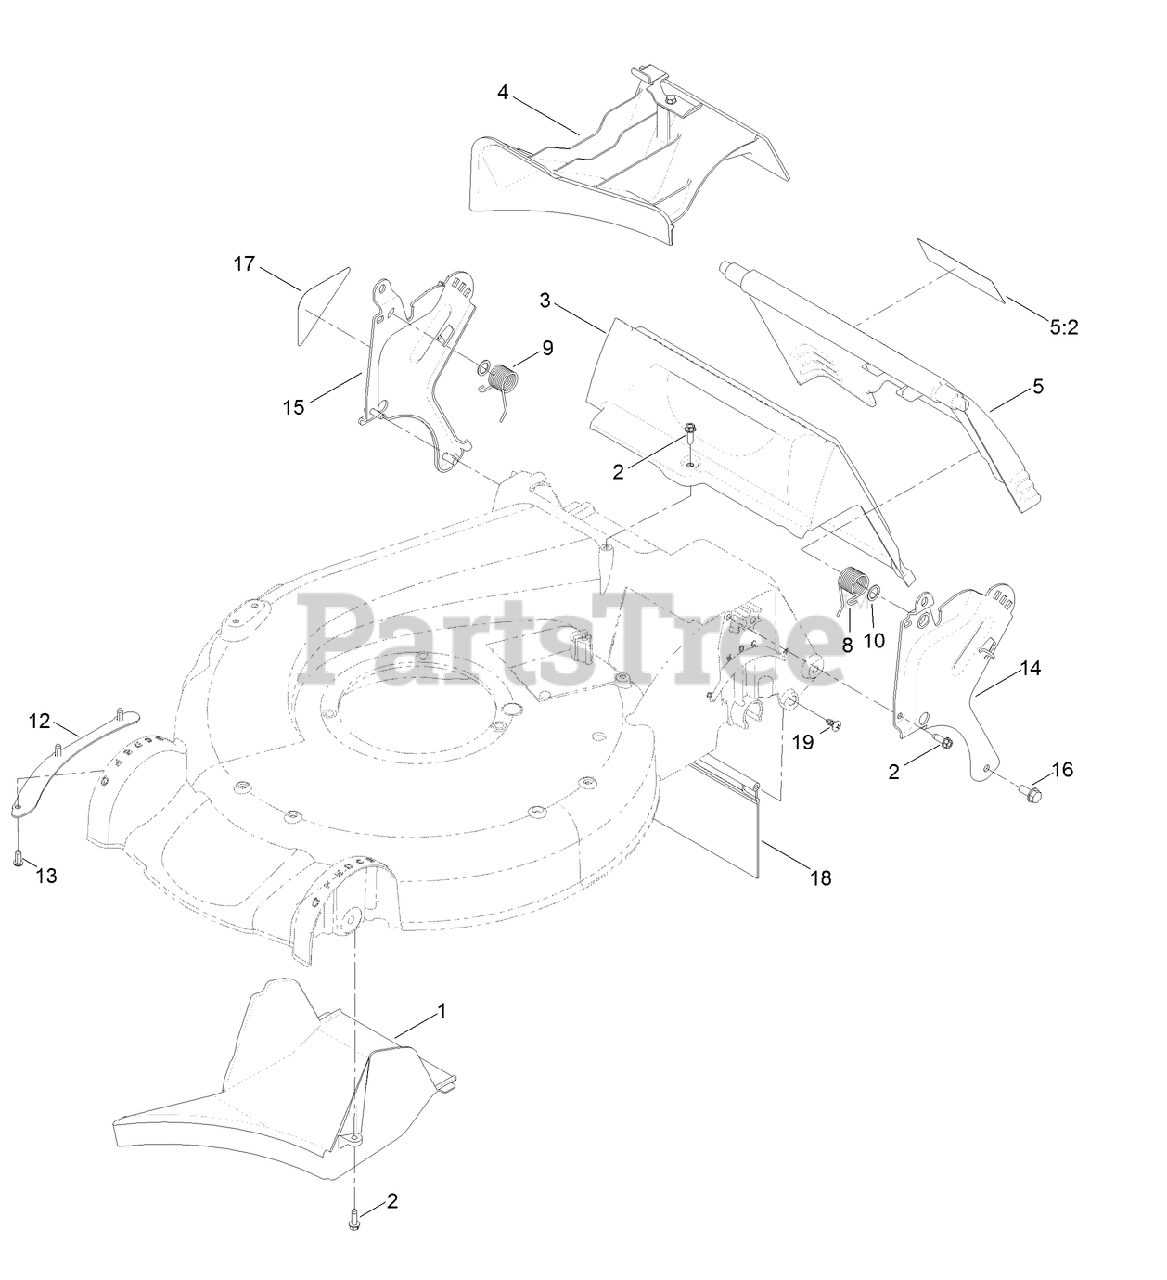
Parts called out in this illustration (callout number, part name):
1	TUNNEL-DISCHARGE
2	SCREW-HWHTF
4	MULCH PLUG ASM
5:2	DECAL-WARNING
8	SPRING-TORSION
9	SPRING-TORSION
10	WASHER-NYLON
12	SHEET-LIP
13	SCREW
14	BRACKET-HANDLE, LH
15	BRACKET-HANDLE, RH
16	SCREW-THD ROLL, HWH
17	DECAL-INSTRUCTION
18	SHIELD-TRAILING
19	SCREW-PTH
